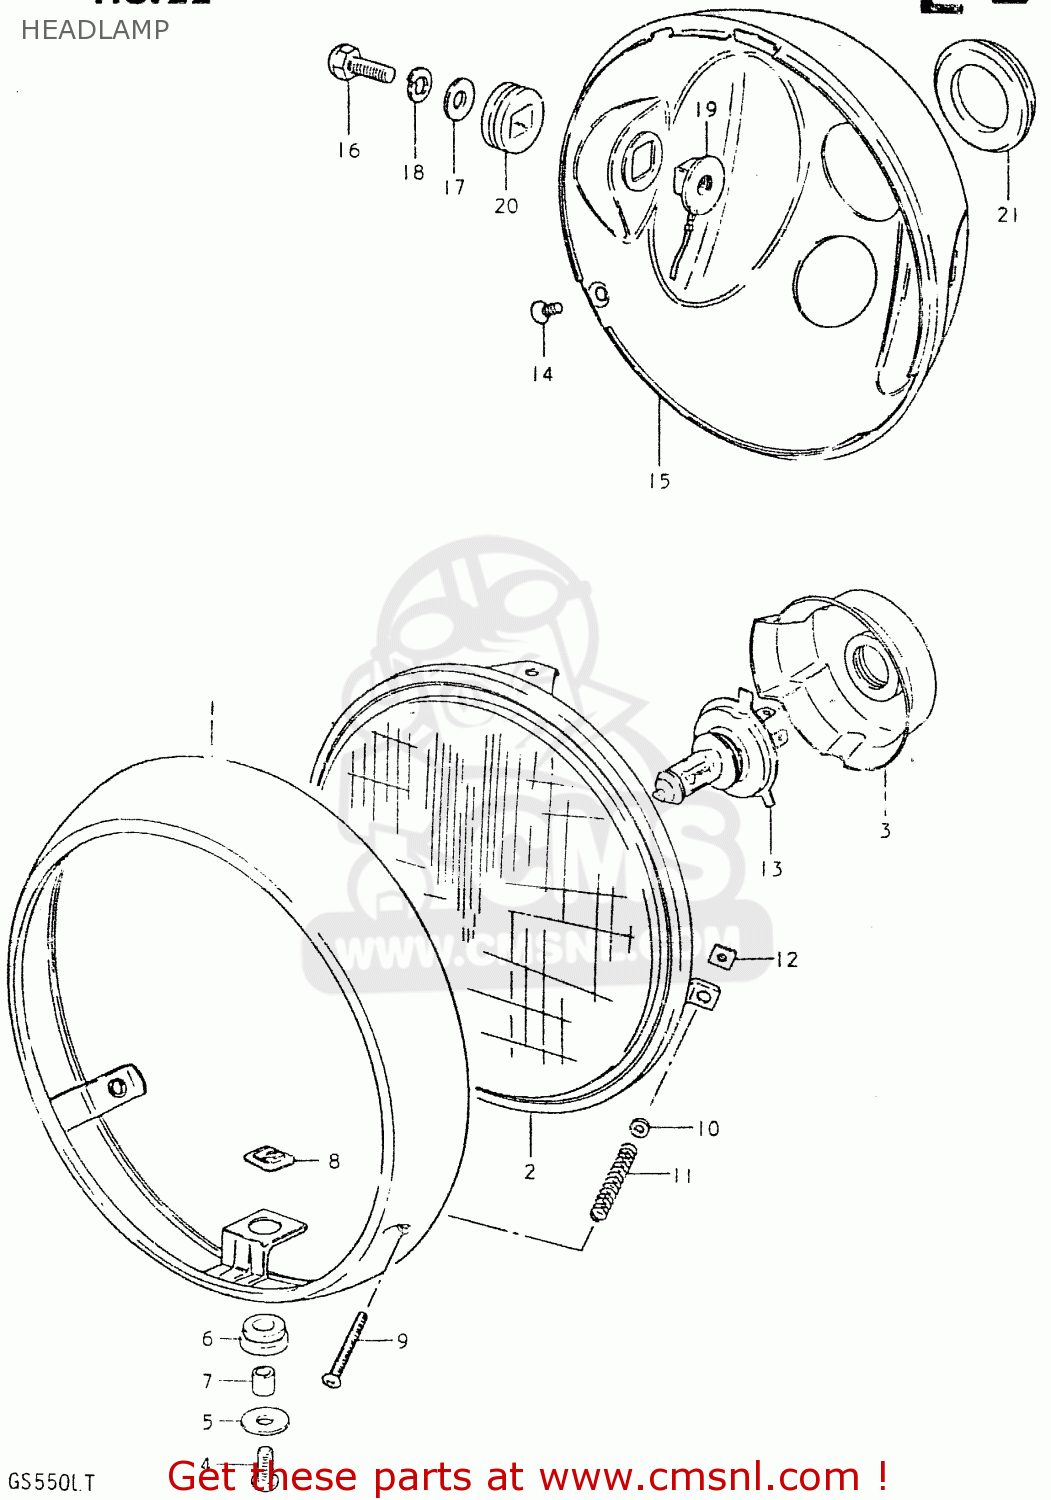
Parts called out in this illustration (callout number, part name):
1	RIM
2	LAMP UNIT
3	COVER,HEADLAMP SOCKET
4	SCREW
5	WASHER
6	CUSHION
7	SPACER
8	NUT
9	SCREW,HEADLAMP ADJUST
10	WASHER
11	SPRING,HEADLAMP ADJUST
12	NUT,HEADLAMP ADJUSTER
13	BULB(12V60/55W,H4)
14	SCREW
15	HOUSING,HEADLAMP
16	BOLT
17	WASHER
18	LOCK WASHER
19	SPACER,HEADLAMP HOUSING
20	CUSHION,HEADLAMP HOUSING
21	GROMMET,HEADLAMP HOUSING
